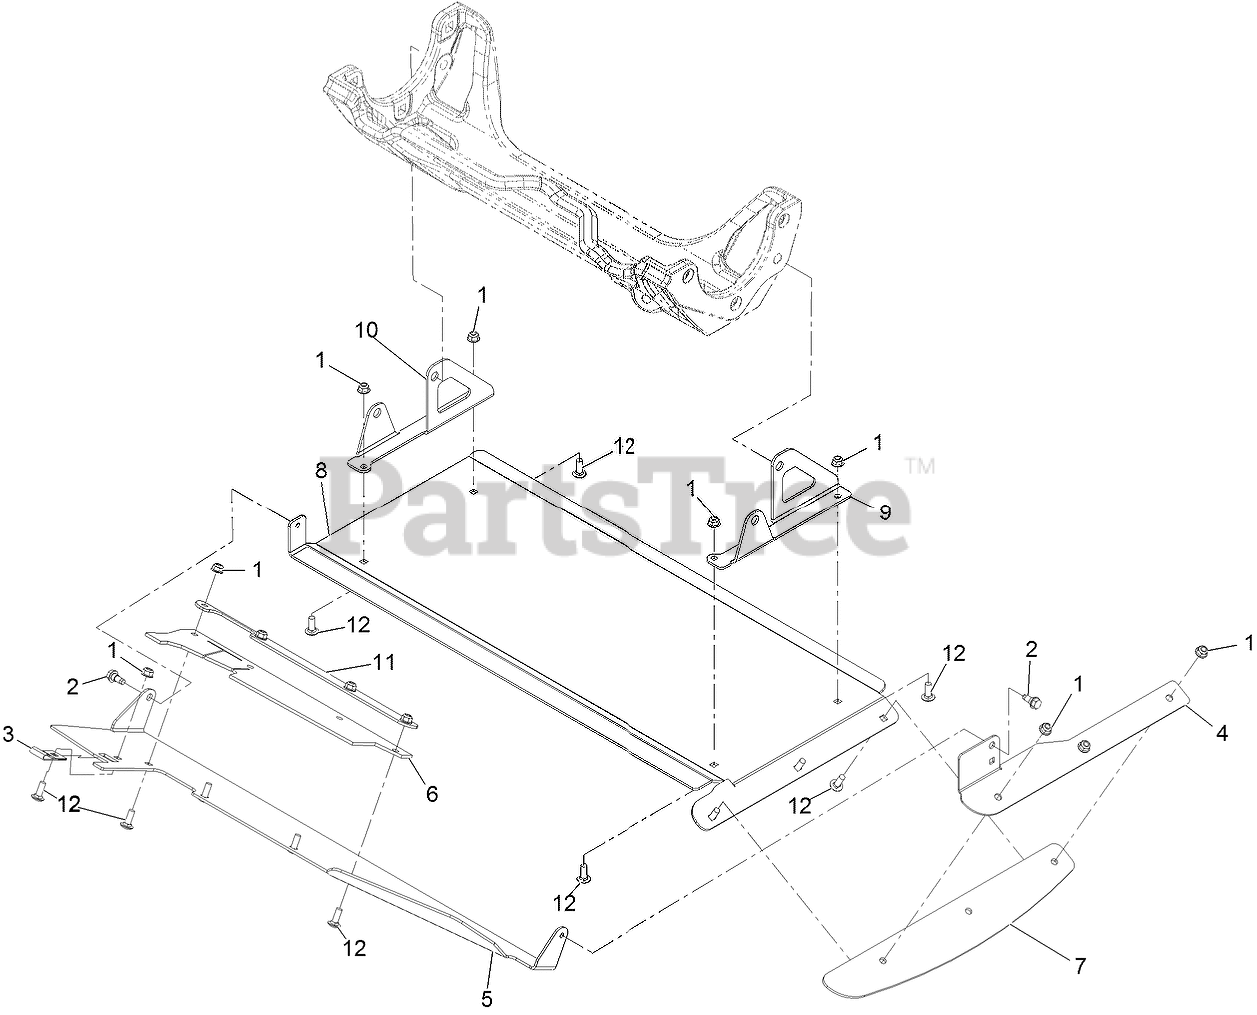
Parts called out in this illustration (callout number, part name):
1	NUT-HF, NI
2	SCREW-SHOULDER
3	BEARING-STRAP, NYLON
4	BRACKET-FLAP, LH
5	PANEL-DISCHARGE
6	Flap-Discharge
7	Flap-Rubber
8	Panel-Discharge
9	BRACKET-TUNNEL HANGER LH
10	BRACKET-TUNNEL HANGER RH
11	SUPPORT-LH FLAP RD96
12	BOLT-CARR
